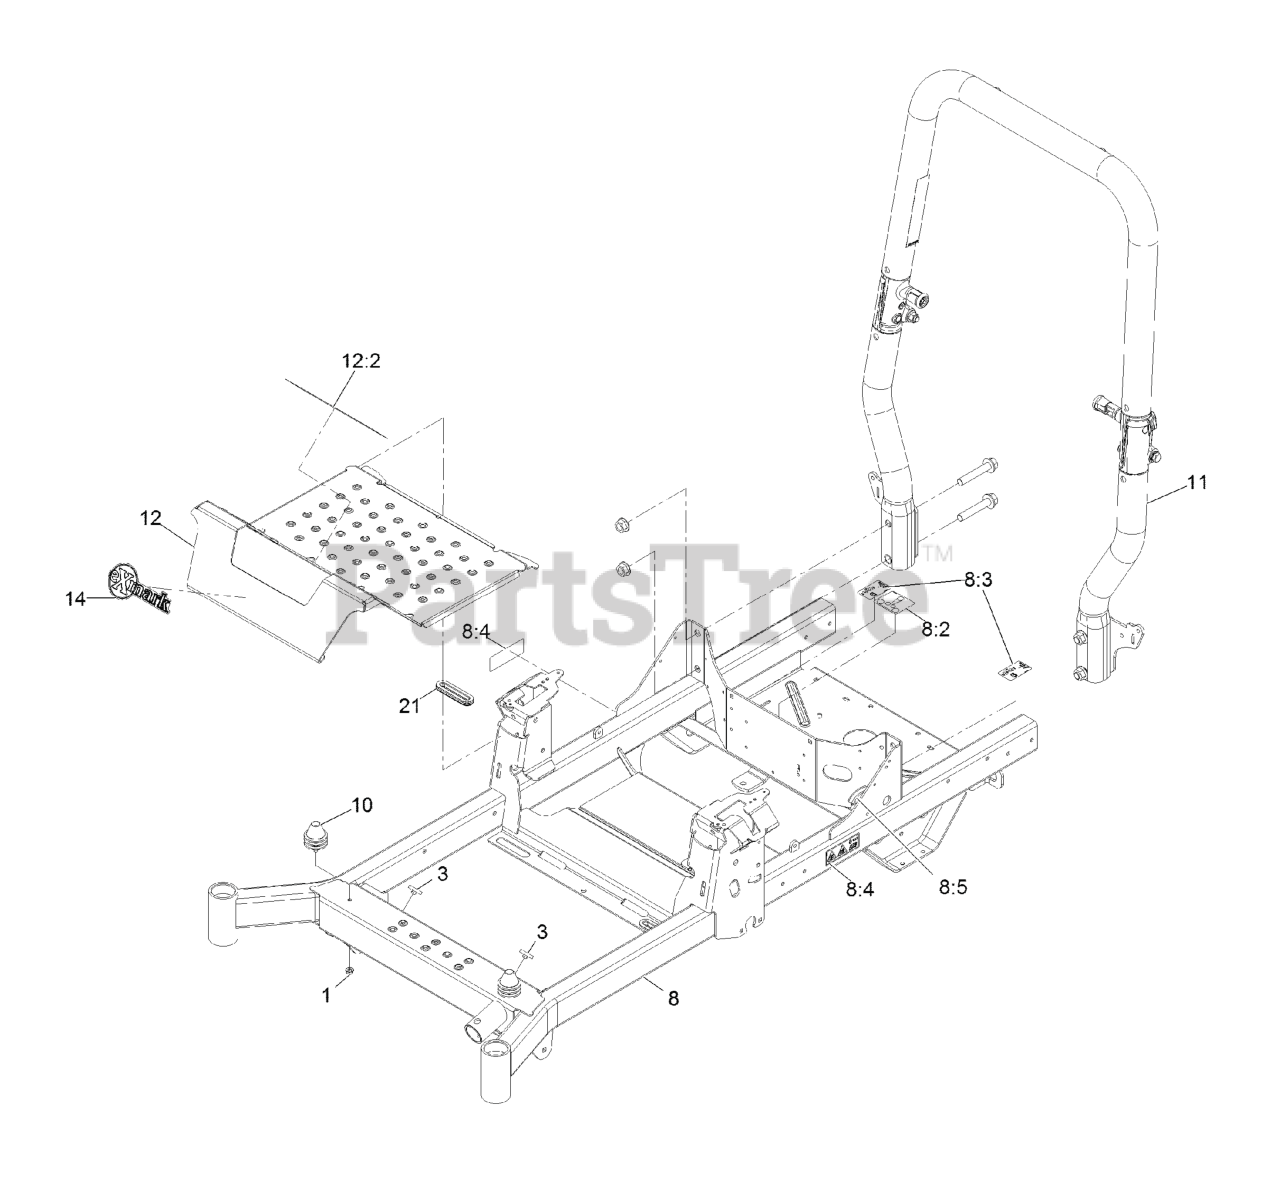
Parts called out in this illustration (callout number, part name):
1	NUT-HF, NI
3	BUMPER-PUSH-IN, RUBBER
8	FRAME ASM
8:2	DECAL-ROUTING, BELT
8:3	DECAL-RELEASE, DRIVE
8:4	DECAL-WARNING
8:5	STRIP-SEAL
10	ISOLATOR
11	ASM-ROPS TAPERED
12	PAN-FLOOR
12:2	DECAL-DANGER
14	DECAL-EXMARK LOGO
21	GROMMET-RUBBER
